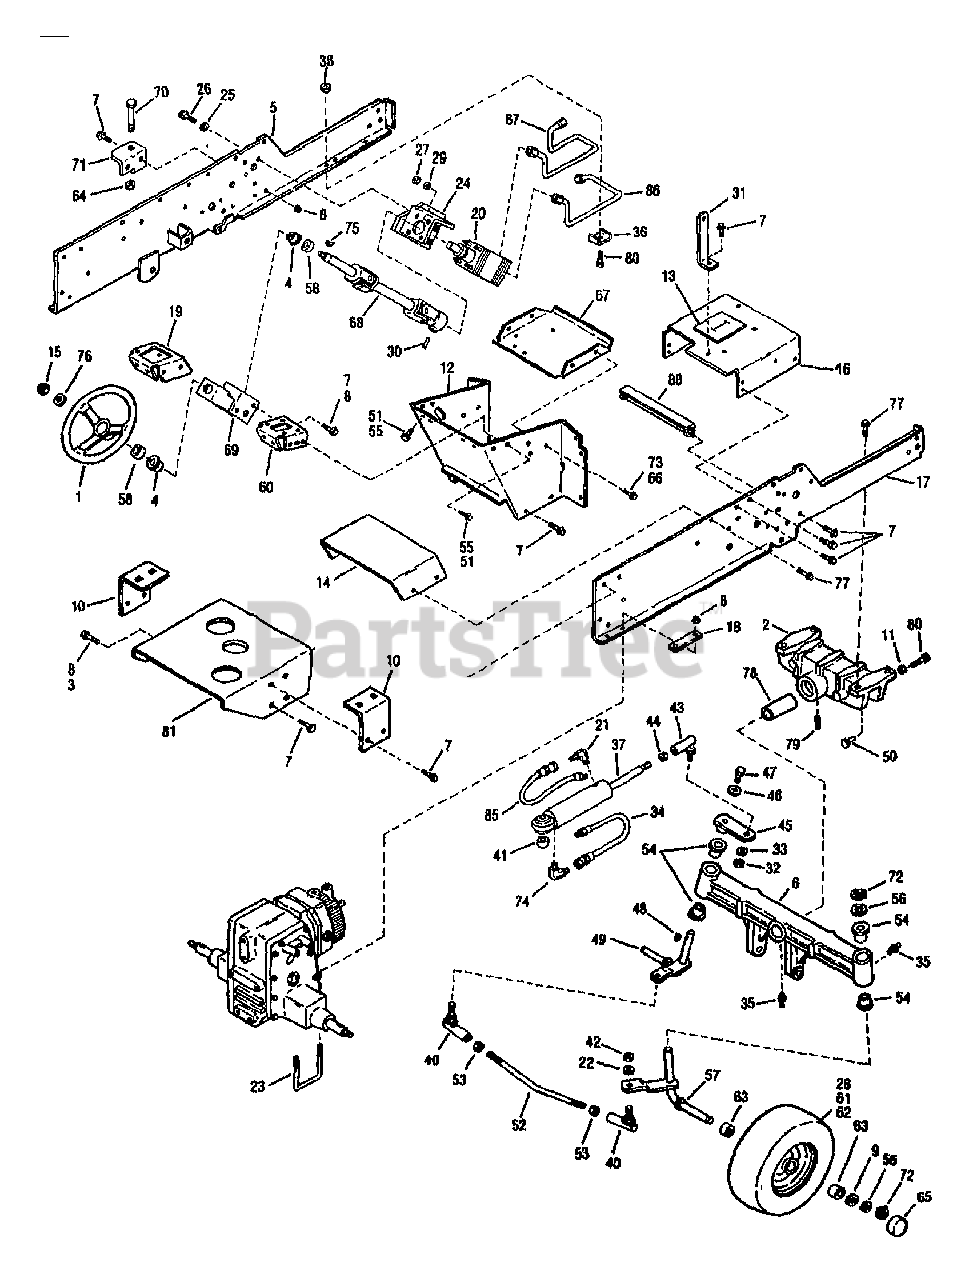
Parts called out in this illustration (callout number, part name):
1	WHEEL-STEERING
2	BOLSTER-FRONT AXLE
3	SCR-HFLK 3/8-16X1.00 ZP
4	BEARING-FLANGED NYLON
6	AXLE-FRONT
8	NUT-HFLK 3/8-16 ZP
9	SPACER-1.75X1.015X.179
10	SUPPORT
11	NUT-HEX JAM 5/16-18
12	SUPPORT
14	TUNNEL W/DECAL
15	NUT-H/LK 3/8-16
16	ASSM-SUPT
18	DOUBLER-REAR
19	BRKT-STEERING
20	KIT-POWER STEERING
21	ELBOW
22	WASHER-LK .5
23	BOLT-U
24	SUPT-STEERING PUMP
25	WASHER-LK .438 ZP
26	SCR-HH 1/2-14X1.00
27	NUT-HEX 5/16-24
28	STEM-VALVE
29	WASHER-LK .312 ZP
30	PIN-ROLL 1/4 X 1-1/4
32	NUT-HEX 5/8-18
33	WASHER-LK 1.072X.634X.156
34	ASSM-HOSE
35	FITTING-GREASE 1/4-28X2.00
36	CLAMP
37	CYLINDER-HYDRAULIC
38	NUT-H/LK 5/16-18
40	JOINT-BALL
42	NUT-H/LK 1/2-20 ZP
43	JOINT-BALL
44	NUT-HEX/JAM 5/8-18 ZP
45	ARM-STEERING
46	WASHER-1.75X.328X.1345
47	SCR-HFLK 5/16-18X.75 ZP
48	KEY-WOODRUFF .25X.875
49	ASSM-SPINDLE
50	PIN-WELD
51	SCR-TRUSS HD 5/16-18X.62
52	ROD-TIE
53	NUT-JAM
54	BEARING-FLANGE
55	NUT-HFLK 5/16-18 ZP
56	WASHER-THRUST
57	ASSM-SPINDLE WHEEL RH
58	COLLAR
60	BRACKET
61	ASSM-WHEEL
62	TIRE-16 X 6.50-8
63	BEARING-BALL
66	SCR-HFLK 1/4-20X.50 ZP
67	CARRIER-BATTERY
68	ASSM-STEERING SHAFT
69	ASSM-SUPPORT
70	SCR-HH 5/8-11X3.0 G5
72	RING-HEAVY EXT HD 1.0 ID
73	NUT-HF/LK 1/4-20 ZP
74	ELBOW
75	KEY-WOODRUFF .188X.75
76	WASHER-FLAT 3/8 SAE
77	SCR-HFLK 3/8-16X1.00 ZP
78	TUBE-PIVOT AXLE
79	PIN-.312X.75
80	SCR-HH 5/16-18X1.0 G5 ZP
81	ASSM-SUPPORT
85	ASSM-HOSE
86	ASSM-TUBE
87	ASSM-TUBE
88	ASSM-FRAME SUPT
